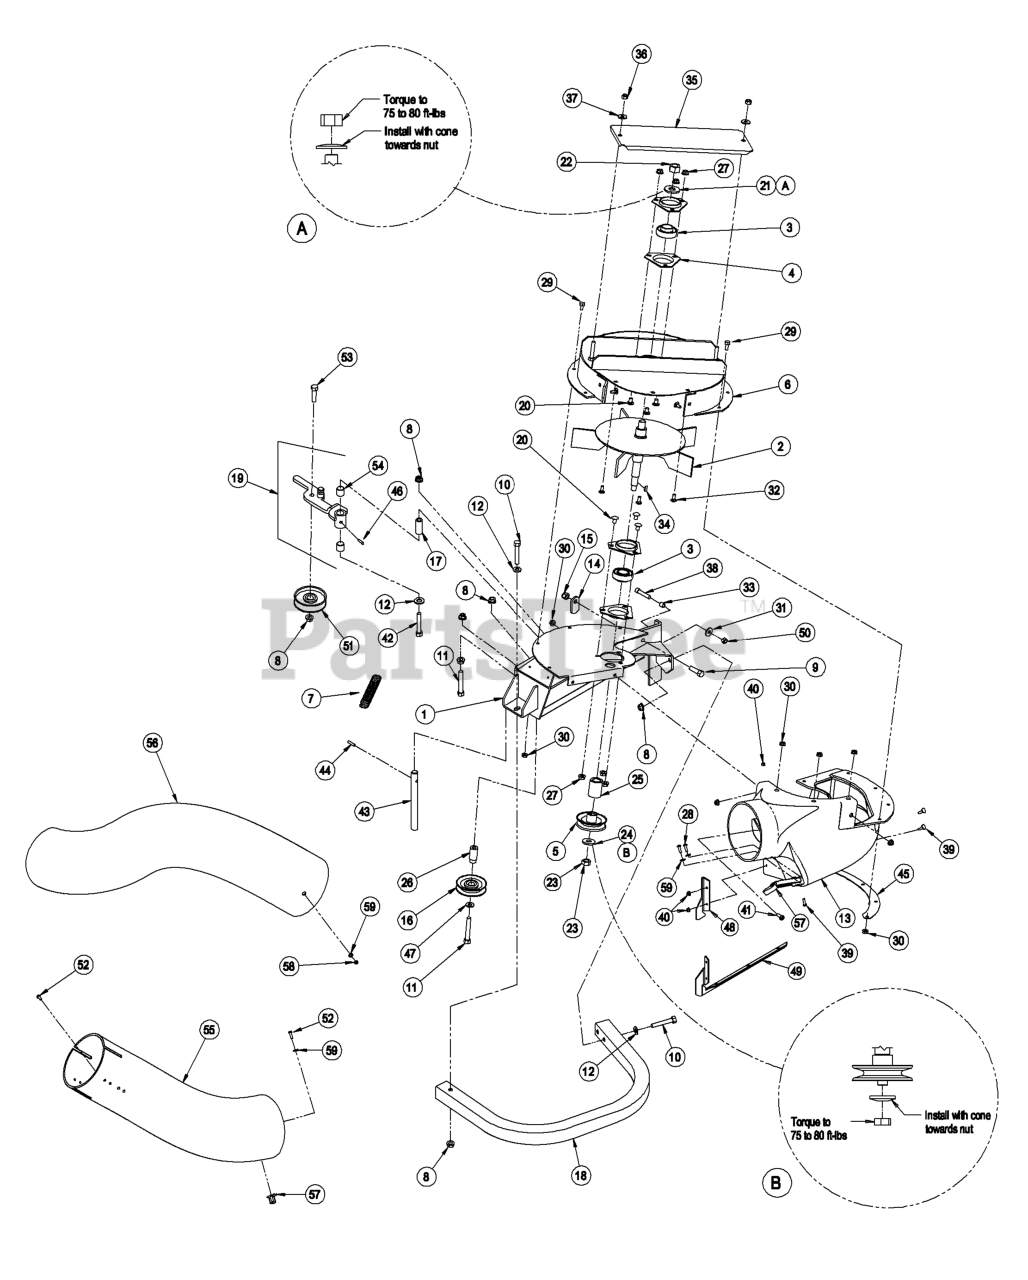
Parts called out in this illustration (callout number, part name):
1	BLOWER MOUNT WLDMT
3	BEARING
4	HOUSING-FLANGE
5	SHEAVE-BLOWER
7	SPRING-IDLER
8	NUT-HHF, WHIZ
9	SCREW-HH
10	SCREW-HH
11	BOLT-CARR
12	WASHER-FLAT
14	LATCH-CATCHER, GRASS
15	NUT-LOCK, NI
16	IDLER-INSIDE
17	BUSHING-PIVOT, IDLER
20	SCREW-CARR
21	WASHER-SPRING
22	NUT-HEX
23	NUT-JAM
24	WASHER-SPRING
28	SCREW-PPH
29	SCREW-HH
31	WASHER-SPRING
32	SCREW-CARR
33	BUSHING, LOCATOR
34	KEY-WOODRUFF
36	NUT-LOCK, NI
37	WASHER-FLAT
38	SCREW-HSH
39	SCREW-HEAD, TRUSS
42	SCREW-HSBH
43	SHAFT-CATCHER, GRASS
44	PIN-ROLL
45	PLATE-BACKING, BLOWER
47	WASHER-FLAT
48	PLATE, FILLER
49	PLATE, BLOCKER
50	NUT-HEX
51	IDLER-FLAT
52	SCREW-PPH
53	SCREW-HH
54	BUSHING
57	LATCH DRAW
58	NUT-LOCK, NI
59	WASHER-FLAT
